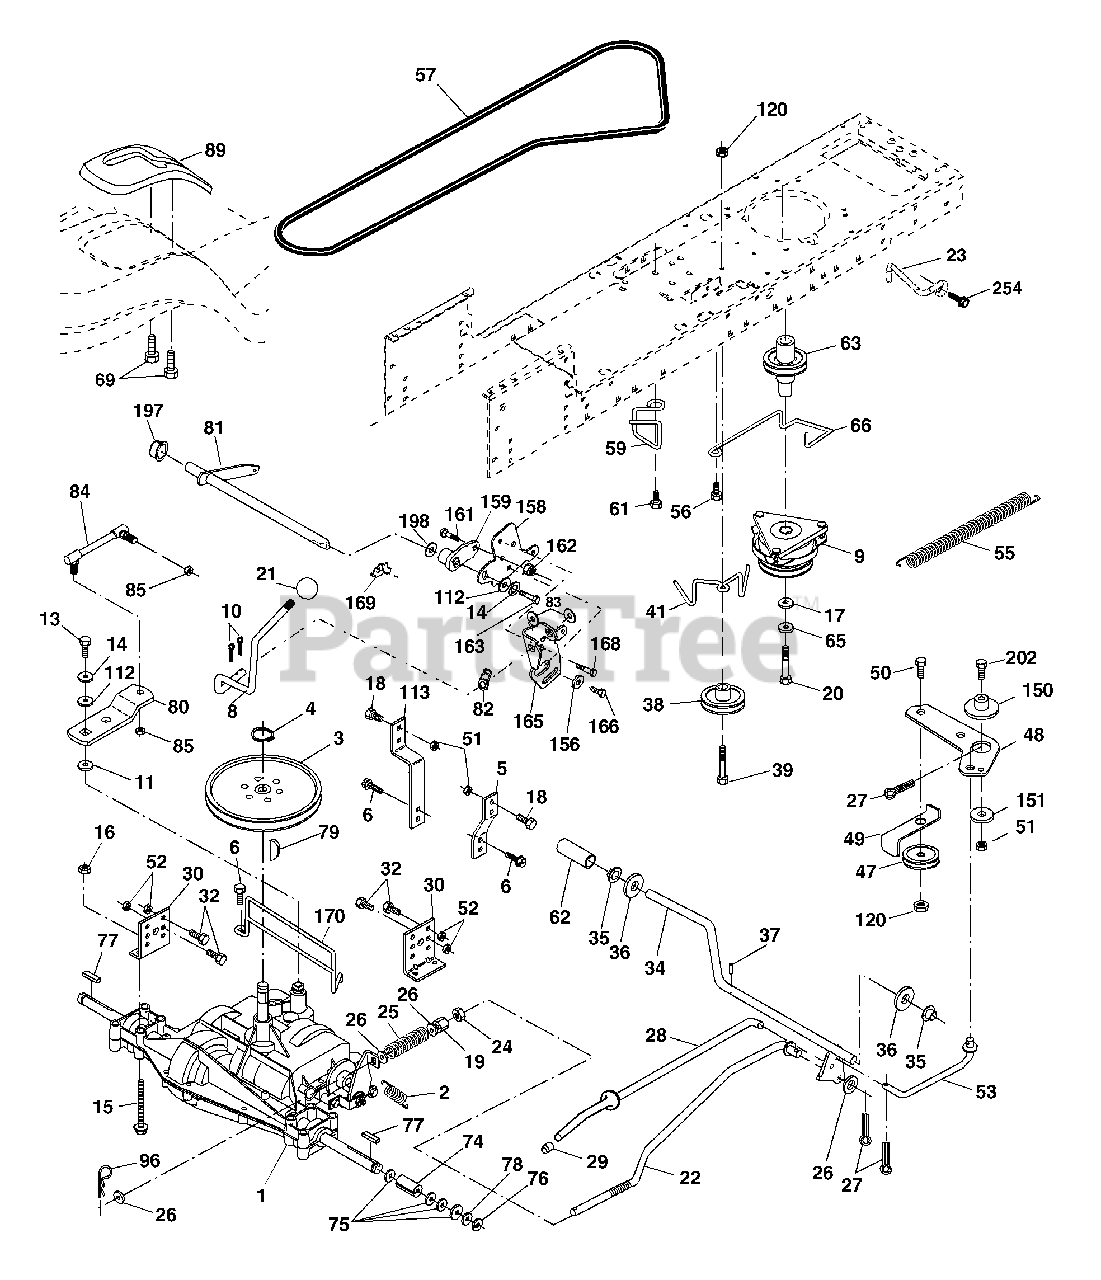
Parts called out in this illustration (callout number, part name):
2	Spring, Return, Brake
3	Pulley, Transaxle
4	Ring, Retainer
5	Strap, Torque
6	Screw 5/16-18 x 3/4
8	Rod Shifter Fender STLT
9	Clutch
10	Pin, Cotter
11	Washer, Shift Plate
13	Bolt 1/4-28 UNF W/Patch Gr. 8
14	Washer Lock Hvy Helical
15	Bolt Hex FLGHD 5/16-18 Gr. 5
16	Nut Lock Hx W/Ins 5/16-18 unc
17	Washer 1-1/2 x 15/32 x .250
18	Bolt Fin Hex 3/8-16 unc x 1 Gr. 5
19	Nut
20	Bolt 7/16-20 x 4 Gr. 5
21	Knob
22	Rod, Brake
23	Bracket Anti-Rotation
24	Nut
25	Spring, Brake Rod
26	Washer
27	Pin
28	Rod, Parking Brake
29	Cap, Parking Brake
30	Bracket, Transaxle
32	Bolt
34	Shaft Assembly, Foot Pedal
35	Bearing, Nylon
36	Washer
37	Roll Pin
38	Pulley, Composite, Flat
39	Bolt Rdhd 3/8-16 unc x 2-3/4
41	Keeper, Belt, Idler
47	Pulley, Idler, V-Groove, Plastic
48	Bellcrank Clutch Grnd Drv Stl
49	Retainer, Belt
50	Bolt
51	Nut Crown Lock 3/8-16 unc
52	Nut Crown Lock 5/16-18 unc
53	Link, Clutch
55	Spring, Clutch Return
56	Screw 3/8-16 x 1-1/4
57	V-Belt, Ground Drive
59	Keeper, Belt, Center Span
61	Screw 3/8-16 x .875
62	Cover, Pedal
63	Pulley, Engine
65	Washer
66	Keeper, Belt, Engine, Fool Proof
69	Screw Hex Wsh Hi-Lo 1/4-1/2 unc
74	Spacer, Axle
75	Washer 25/32 x 1-1/4 x 16 Ga.
76	E-Ring
77	Key, Square 2.0 x .1845/1865
78	Washer 25/32 x 1-5/8 x 16 Ga.
79	Key Woodruff
80	Arm, Shift
81	Shaft Asm Cross Tapered 20
82	Spring, Torsion
83	Washer 17/32 x 3/4 x 16 Ga.
84	Link Transaxle
85	Nut, Nylock
89	Console, Shift, STLT
96	Retainer Spring 1"
112	Washer 9/32 x 3/4 x 10 Ga.
113	Strap Torque 90 Degrees
120	Nut Lock Flg. 3/8-16 unc
150	Spacer Retainer
151	Washer 13/32 x 2 x 10 Ga.
156	Washer Srrted 5/16 ID x 1.125
158	Bracket Shift Mount
159	Hub Shift
161	Bolt Rdhd Sqnk 1/4-20 x 3/4 Gr.5
162	Nut Crownlock 1/4-20 unc
163	Bolt Hex Fin 1/4-20Unc x 1 Gr. 5
165	Bracket Pivot Lever
166	Screw 5/16-18 x 5/8 TT Yellow
168	Bolt Shoulder 5/16-18 x .561
169	Plate Fastening Lt
170	Keeper Belt Transaxle Gear
197	Nyliner Snap-In 5/8 ID
198	Washer Nyliner 7/8 ID x .105 Hd
202	Bolt Carr. SH 3/8-16 x 1-3/4 Gr. 5
254	Screw 3/8-16 x 1
